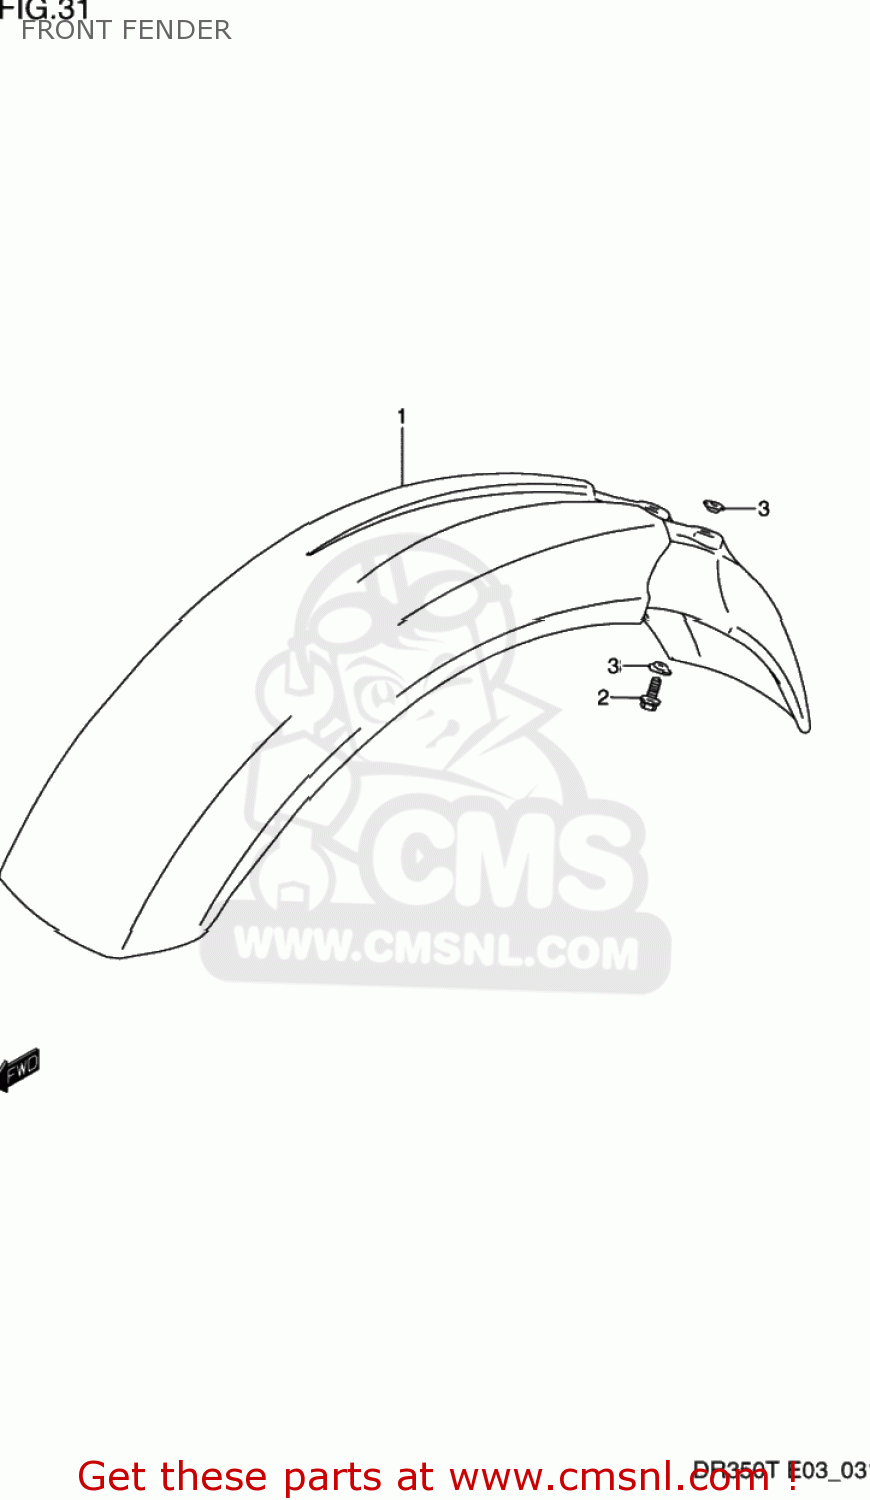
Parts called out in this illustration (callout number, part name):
1	FENDER,FR
2	BOLT
3	WASHER
